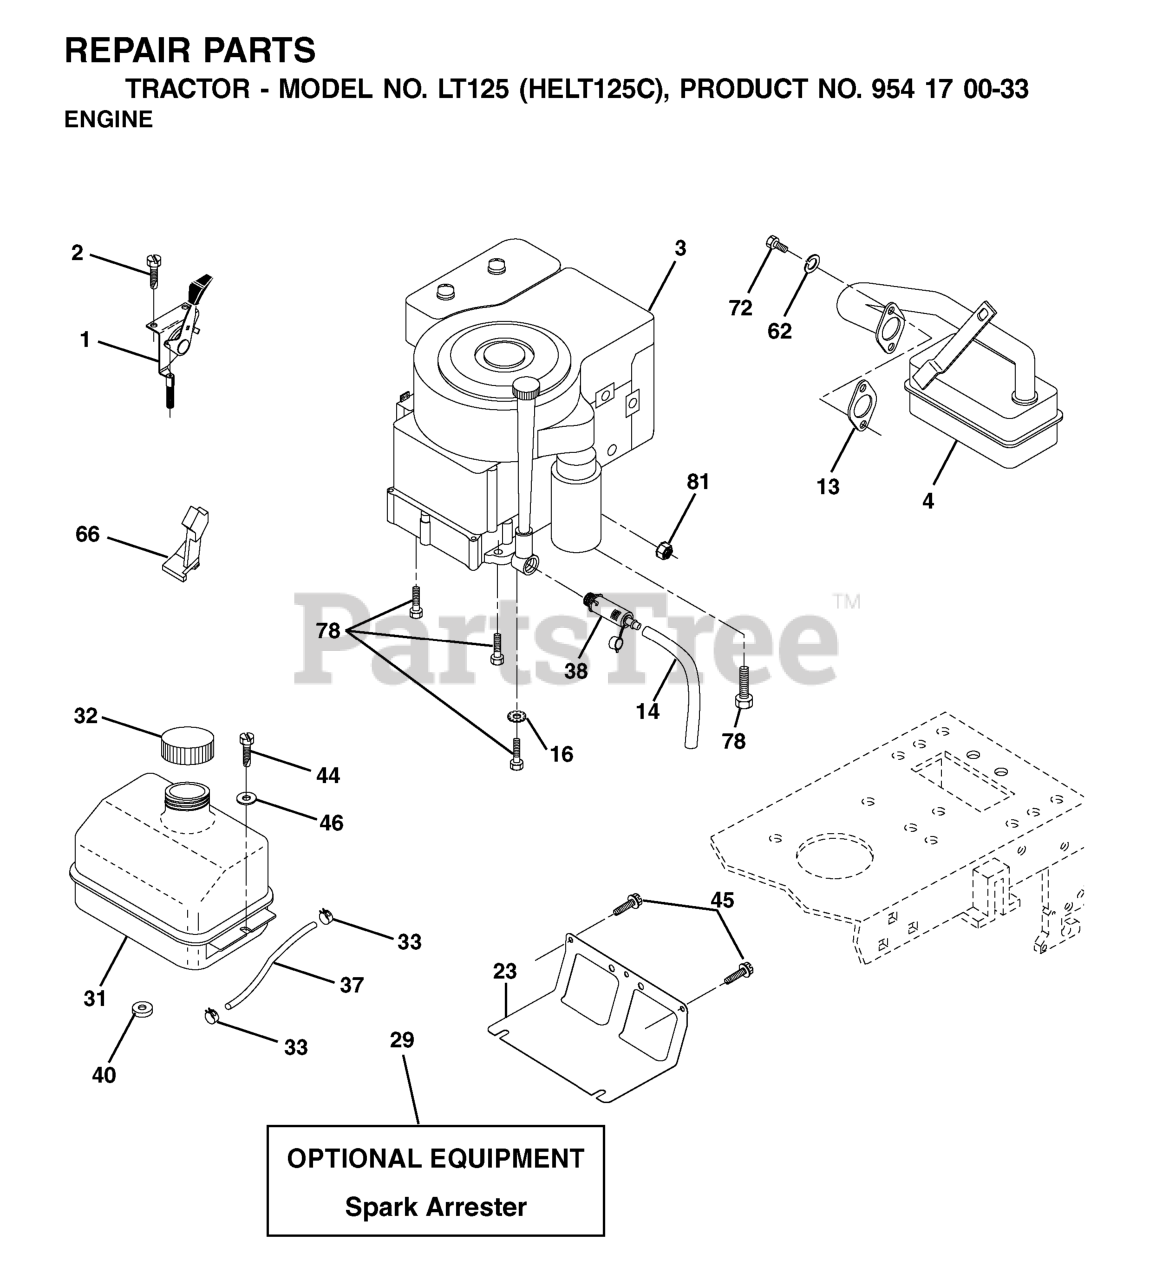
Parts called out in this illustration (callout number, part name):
1	THROTTLE.CONTROL.CABLE.BLACK
2	SCREW
4	MUFFLER.SINGLE.B&S.10-12HP
13	REPL BY 532 27 22-93
14	TUBE, DRAIN OIL ASM.
16	LOCKWASHER
23	SHIELD.BROWNING.DBR.GUARD
29	KIT.SPARK ARRESTOR 794945 B&S
31	TANK FUEL LT
32	FUEL CAP
33	HOSE CLAMP
37	LINE.FUEL.20
38	PLUG, OIL DRAIN EASY
40	BUSHING.SNAP.NYL.BLK.
44	SCREW HEXWSHR 1/4-20X3/4
45	SCREW, 3/8-16X3/4
62	WASHER.LOCK.HVY.HLCL.SPR.5/16
66	STOP THROTTLE
72	SCREW
78	SCREW.3/8-16
81	NUT
